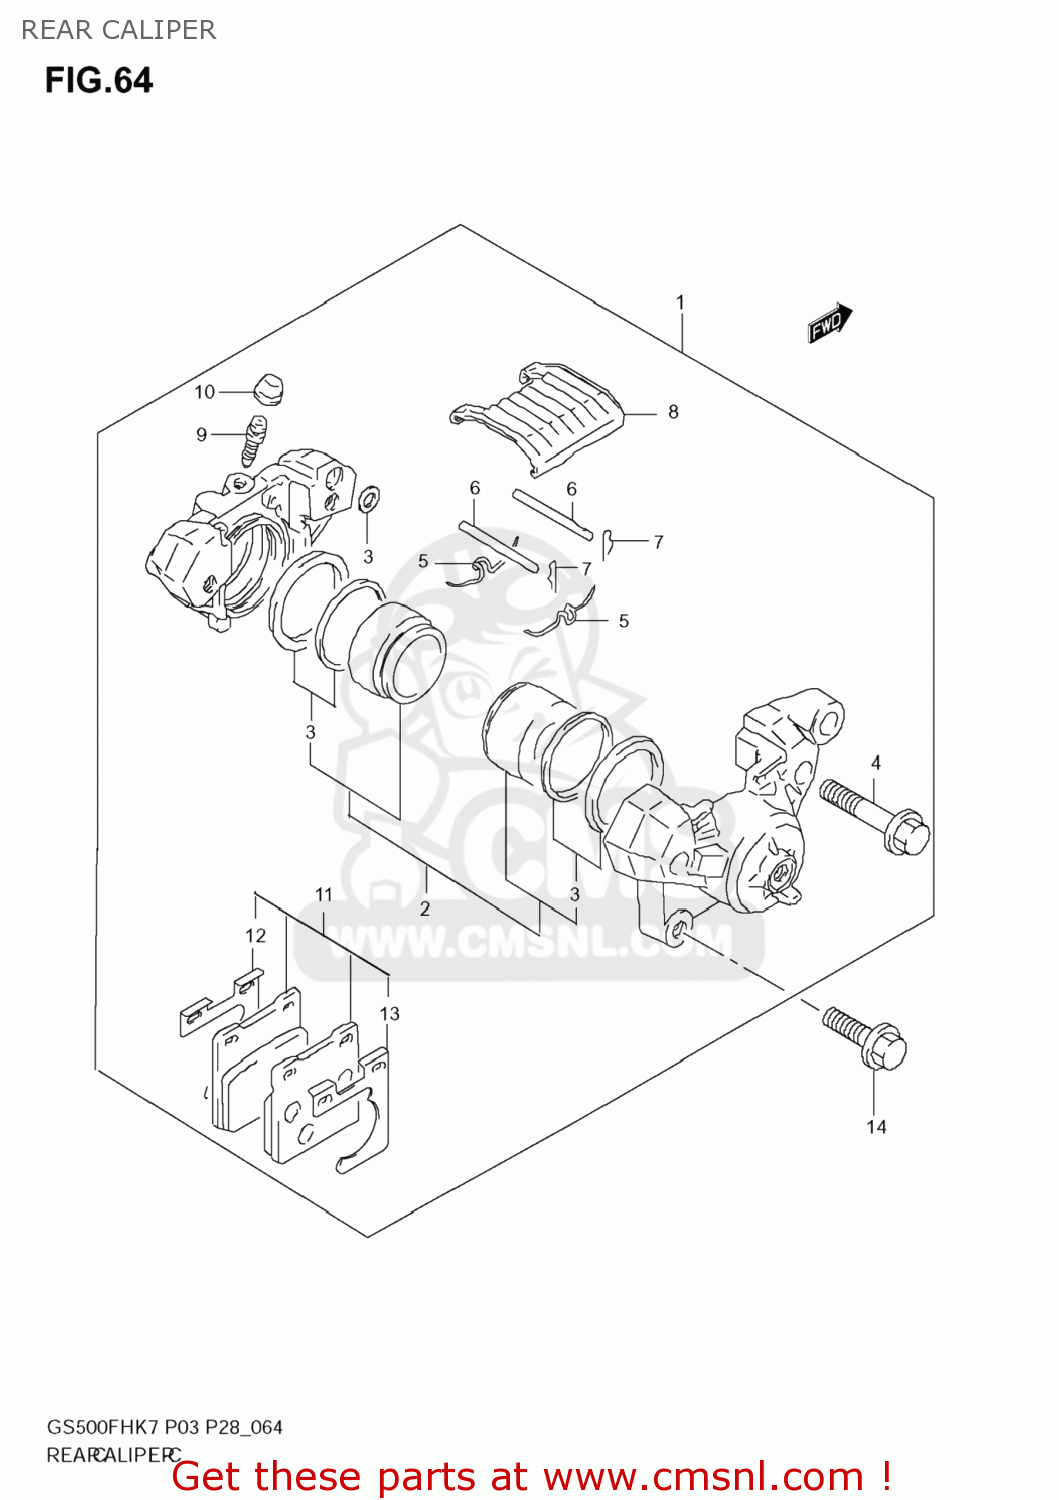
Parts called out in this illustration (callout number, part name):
1	CALIPER ASSY
2	PISTONSET
3	SEAL SET PIST.
4	BOLT
5	SPRING
6	PIN
7	CLIP
8	COVER
9	BLEEDER
10	CAP
11	PAD/SHIMSET
12	SIM PAD
13	SHIM, OUTER
14	BOLT
